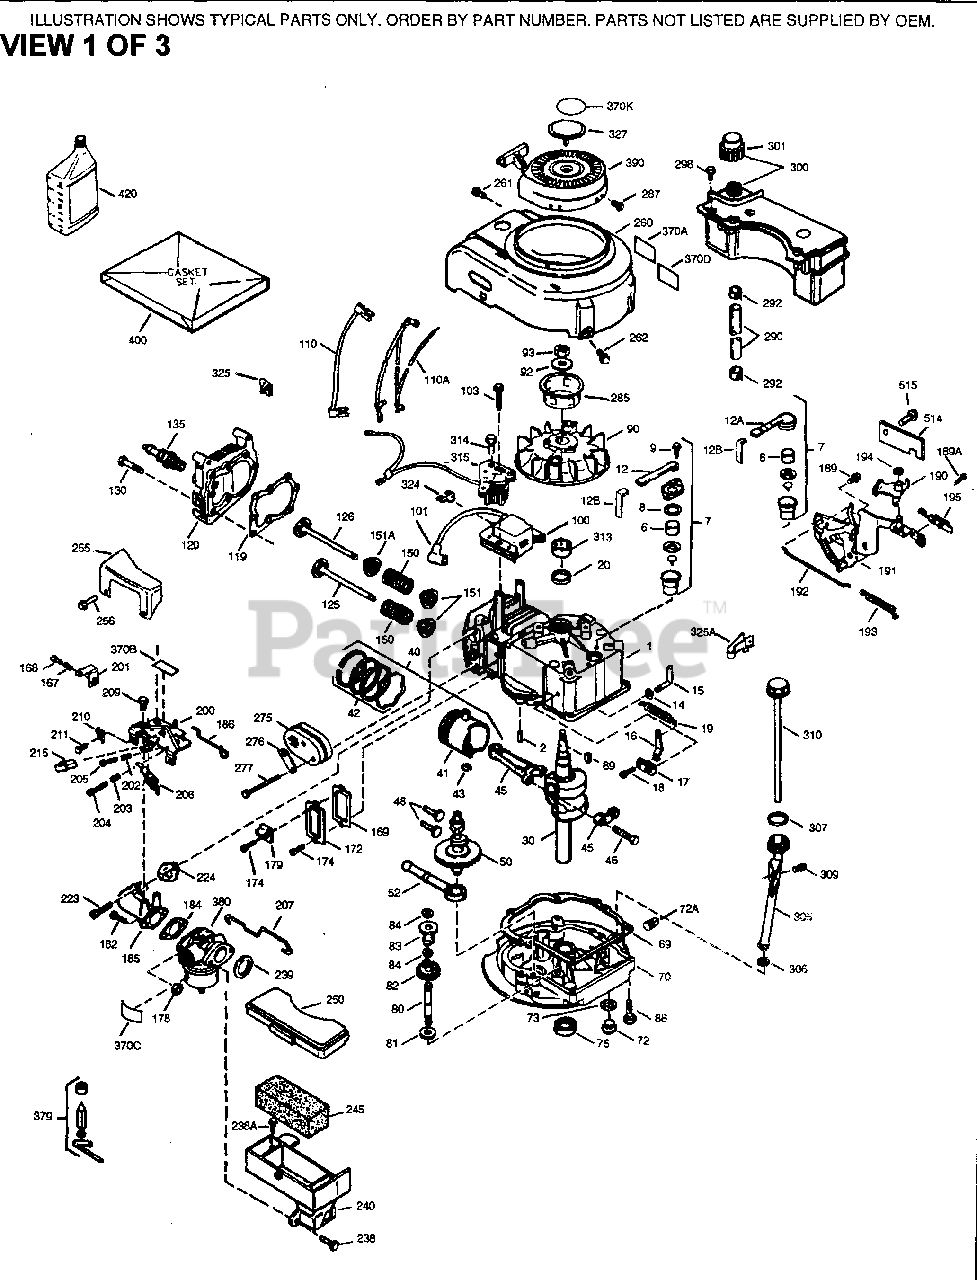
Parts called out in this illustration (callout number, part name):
1	"Cylinder (Incl. 2, 20 & 125)
2	Dowel Pin
6	Breather Element
7	Breather Ass'y. (Incl. 6,8,9,12,12B)
8	* Breather Gasket
9	Screw, 10-24 x 9/16"
12	Breather Tube
12B	Breather Tube Elbow
14	Flat Washer
15	Governor Rod (Incl. 14)
16	Governor Lever
17	Governor Lever Clamp
18	Screw, 8-32 x 5/16"
19	Extension Spring
20	Oil Seal
30	Crankshaft
40	Piston, Pin & Ring Set (Std.) (Incl. 41, 42 & 43)
40	Piston, Pin & Ring Set (.010" OS) (In cl. 41, 42 & 43)
40	Piston, Pin & Ring Set (.020" OS) (In cl. 41, 42 & 43)
41	Piston & Pin Assembly (Std.) (Incl. 4 3)
41	Piston & Pin Assembly (.010" OS) (Inc l. 43)
41	Piston & Pin Assembly (.020" OS) (Inc l. 43)
42	Ring Set (Std.)
42	Ring Set (.010" OS)
42	Ring Set (.020" OS)
43	Piston Pin Retaining Ring
45	Connecting Rod Ass'y (Incl. 46)
46	Connecting Rod Bolt
48	Valve Lifter
50	Camshaft (MCR)
52	Oil Pump Ass'y.
69	* Mounting Flange Gasket
70	Mounting Flange (Incl. 58,72 thru 83)
72	Oil Drain Plug
75	Oil Seal
80	Governor Shaft
82	Governor Gear Ass'y. (Incl. 81)
83	Governor Spool
86	Screw, 1/4-20 x 1-1/4"
89	Flywheel Key (also available in Packa ged Part #740007B)
90	Flywheel
92	Belleville Washer
93	Flywheel Nut
100	Solid State Ignition
101	Spark Plug Cover
103	Screw, Torx T-15, 10-24 x 1"
110	Ground Wire
119	* Cylinder Head Gasket
120	Cylinder Head
125	Exhaust Valve (Std.) (Incl. 151)
125	Exhaust Valve (1/32" OS) (Incl. 151)
126	Intake Valve (Std.) (Incl. 151)
126	Exhaust Valve (1/32" OS) (Incl. 151)
130	Screw, 5/16-18 x 1-1/2"
135	Resistor Spark Plug (RJ19LM) also ava ilable in Packaged Part #740081
150	Valve Spring
151	Valve Spring Cap
169	* Valve Cover Gasket
172	Valve Cover
174	Screw, 10-24 x 9/16"
178	Nut & Lock Washer 1/4-28
182	Screw, 1/4-28 x 7/8"
184	* Carburetor To Intake Pipe Gasket
185	Intake Pipe (Incl. 224)
186	Governor Link
189	Screw, 1/4-20 x 3/8"
190	Brake Lever
191	S.E. Brake Bracket (Incl. 195)
192	Brake Control Link
193	Brake Spring
194	Retaining Ring
195	Terminal
200	Control Bracket (Incl. 202 thru 205)
202	Compression Spring
203	Compression Spring
204	Screw, 5-40 x 7/16"
205	Screw, 6-32 x 21/32"
207	Throttle Link
209	Screw, 10-24 x 9/16"
215	Control Knob
223	Screw, 1/4-20 x 1"
224	* Intake Pipe Gasket
238	Screw, 10-32 x 49/64"
239	* Air Cleaner Gasket
245	Air Filter (Paper) (also available in Packaged Part #740095 (Qty.2))
250	Air Filter Cover (Craftsman)
260	Blower Housing
261	Screw, 10-24 x 9/16"
262	Screw, 1/4-20 x 1/2"
275	Muffler (Incl. 277)
277	Screw, 1/4-20 x 2-13/64"
285	Starter Cup
287	Screw, 8-32 x 21/64"
290	Fuel Line
292	Fuel Line Clamp
298	Screw, 10-32 x 35/64"
300	Fuel Tank (Incl. 292 & 301)
301	Fuel Cap (Red)
305	Oil Fill Tube
306	* "O"-Ring
307	"O" Ring
309	Screw, 10-32 x 1/2"
310	Dipstick
327	Starter Plug this)
354	Staple
370A	Lubrication Decal
370B	Control Decal
380	Carburetor (Incl. 184)
390	Rewind Starter NOTE: This engine cou ld have been built with 590686 starte r. Refer to the design of the air int ake louvers for part identification. Individual starter parts do not inter change.
400	* Gasket Set (Incl. items marked PK in notes) Incl. part #'s: 26756 (1), 272 34A (1), 33735 (1), 34265 (1), 34338 (1), 34690A (1), 35261 (1), 36440 (1) .
999	Summer Maintenance Kit (incl. Oil, Sp ark Plug, Air Cleaners (2), & Ultra-F resh)
